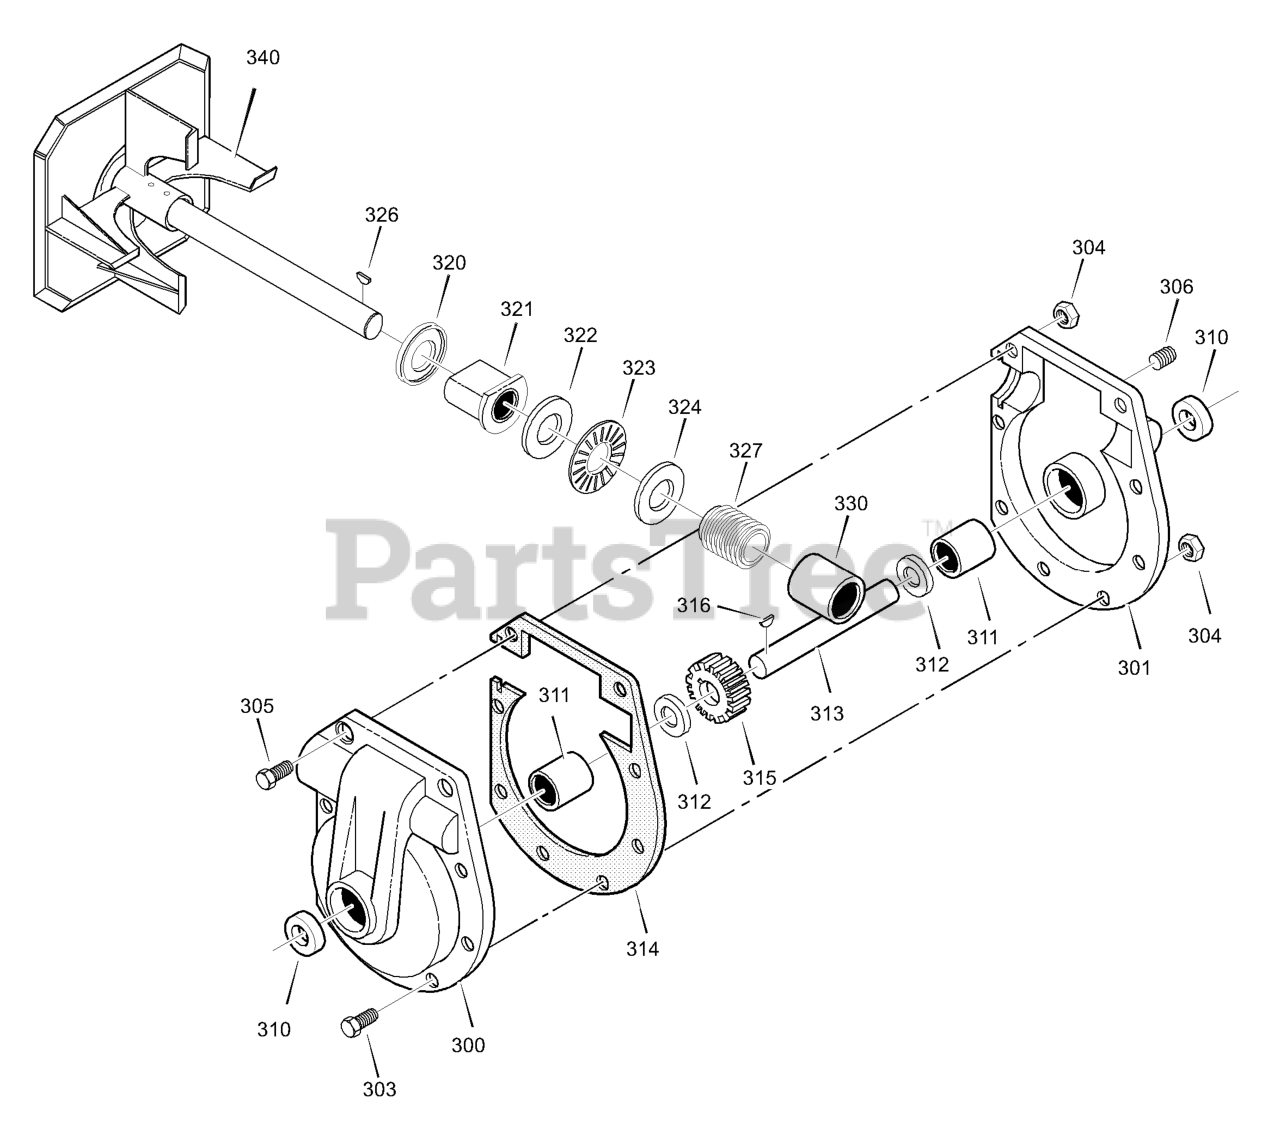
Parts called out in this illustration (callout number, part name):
300	CASE, GEAR, RH
301	CASE, GEAR, LH
303	SCREW, 5/16-24 x 1.00
304	NUT, 5/16-24
305	SCREW, 5/16-18 x 1.50
306	PLUG, PIPE 1/4-18
310	SEAL, OIL
311	BEARING, SLEEVE
312	WASHER, FLAT
313	SHAFT, AUGER OUTPUT
314	GASKET, GEAR BOX
315	GEAR, WORM
316	KEY, WOODRUFF #61
320	RING, QUAD.
321	BEARING, FL
323	BEARING, ROLLER
340	IMPELLER
